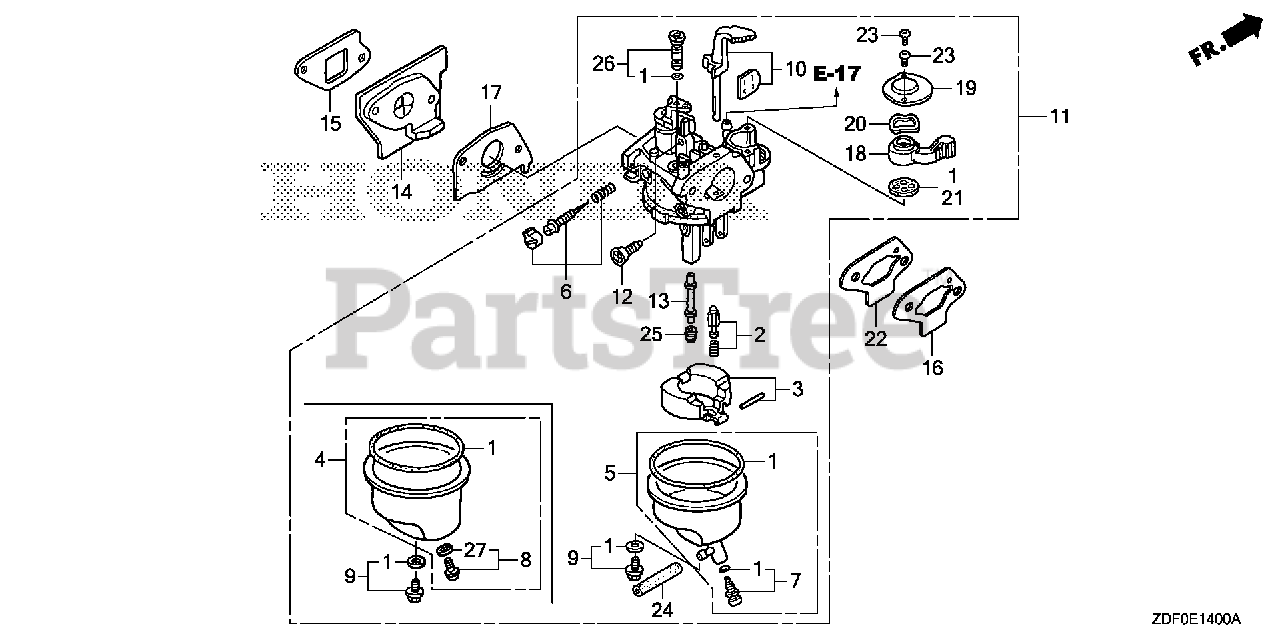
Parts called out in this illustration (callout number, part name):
1	GASKET SET
2	VALVE SET, FLOAT (CARBURETOR NO.) (SEAT NOT INCLUDED)
4	CHAMBER SET, FLOAT (CARBURETOR NO.)
6	SCREW SET
8	SCREW SET, DRAIN (Honda Code 1672187). (CARBURETOR NO.)
9	SCREW SET (CARBURETOR NO.)
10	CHOKE SET (CARBURETOR NO.)
11	CARBURETOR ASSY. (BF32E G)
12	SCREW, THROTTLE STOP
13	NOZZLE, MAIN (CARBURETOR NO.)
14	INSULATOR, CARBURETOR
15	GASKET, INSULATOR (ENGINE NO.)
17	GASKET, CARBURETOR
18	LEVER, VALVE (CARBURETOR NO.)
19	PLATE, LEVER SETTING (CARBURETOR NO.)
20	SPRING, PETCOCK LEVER (CARBURETOR NO.)
21	GASKET, VALVE
22	GASKET, AIR CLEANER
23	SCREW, PAN (3X6)
25	JET, MAIN (#48) (CARBURETOR NO.)
25	JET, MAIN (#50) Use from Engine SN BF12A B.
25	JET, MAIN (#52) Use from Engine SN BF12A B.
26	JET SET, PILOT (#35)
